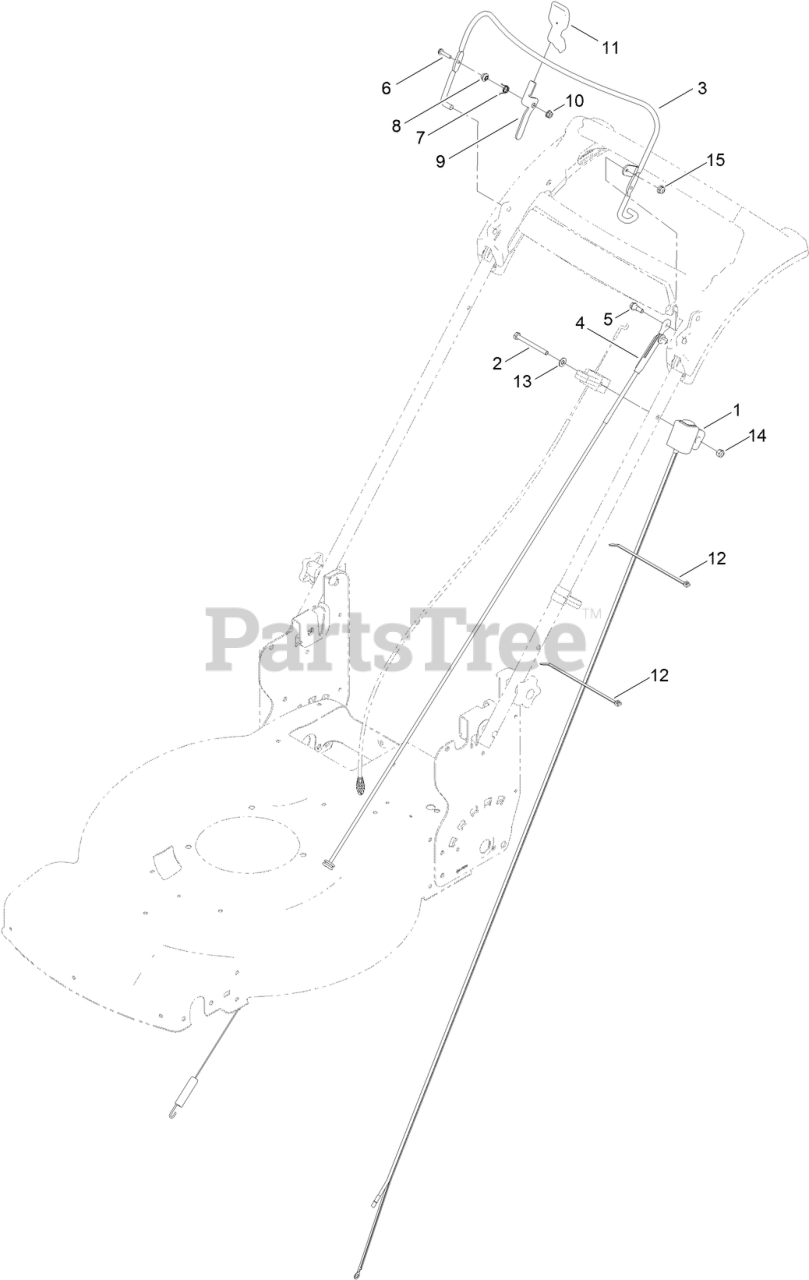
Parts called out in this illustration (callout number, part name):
1	SWITCH HOUSING ASM
2	SCREW-HH
3	BAIL-BRAKE [BLACK]
4	CABLE-BRAKE
5	BOLT-SHOULDER
6	SCREW-HWH
7	SPRING-TORSION
8	SPACER
10	NUT-HEX FLANGE
12	TIE-CABLE
13	WASHER-FLAT
14	NUT-HEX
15	NUT-HF
